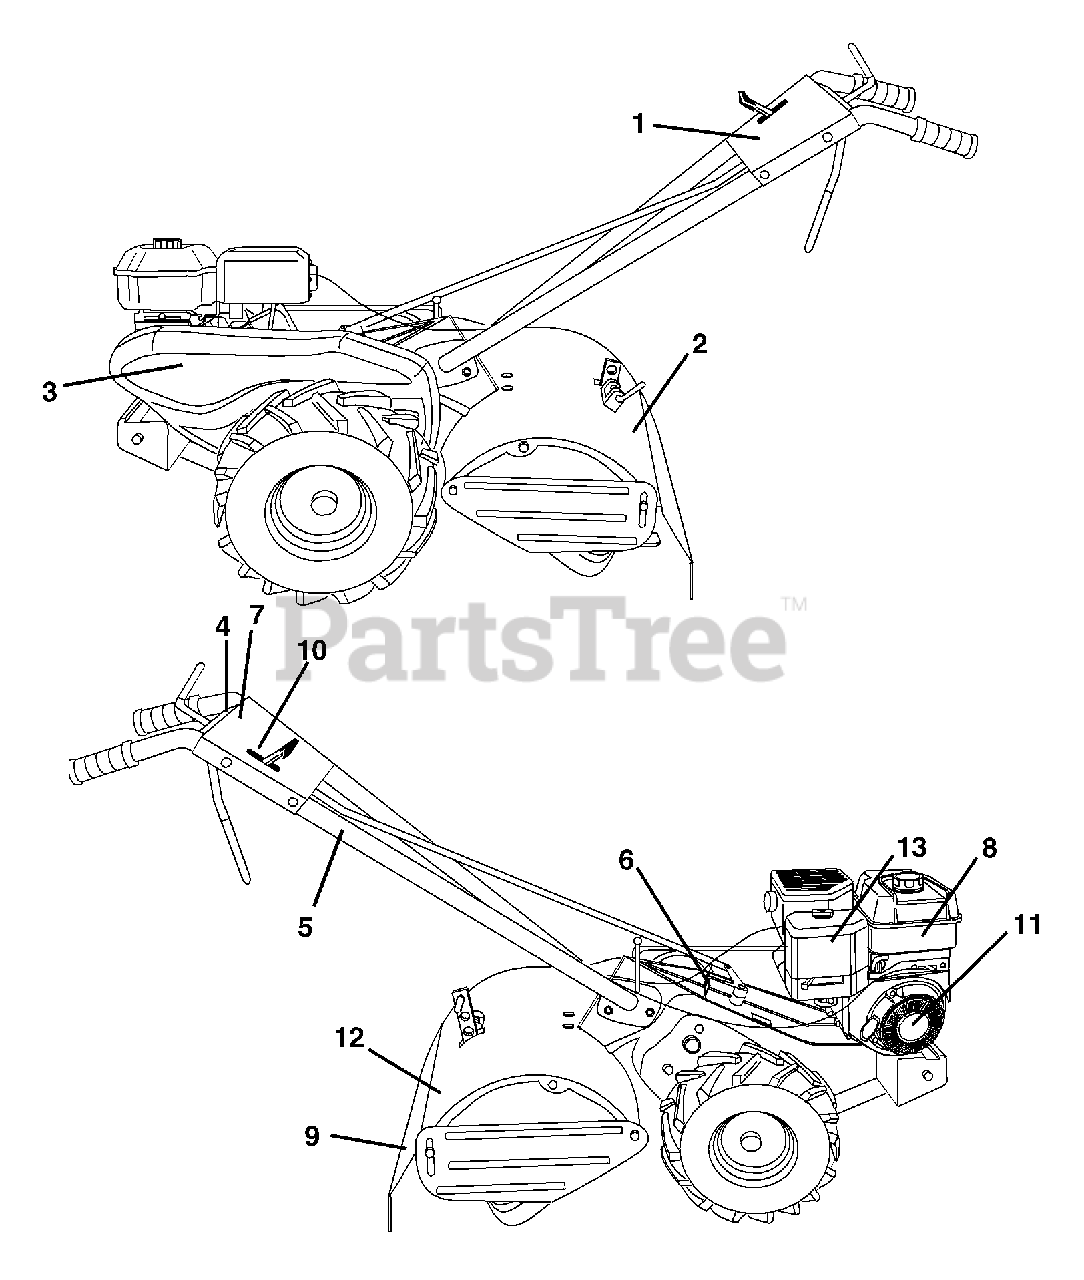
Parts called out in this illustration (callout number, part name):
1	Decal, Logo
2	Decal, Logo
3	Decal, Logo
4	Decal, Instruction, Tilling
5	Decal, Hand Placement
6	Decal, Shift Indicator
7	Decal, Pnl Cntrl Reverse
8	Decal, OHV.N-I/C
9	Decal, Warning, Rotating Tines
10	Decal, Throttle
11	Decal, Rewind Intek
12	Decal, Warning Till
13	Decal, B&S Tiller
